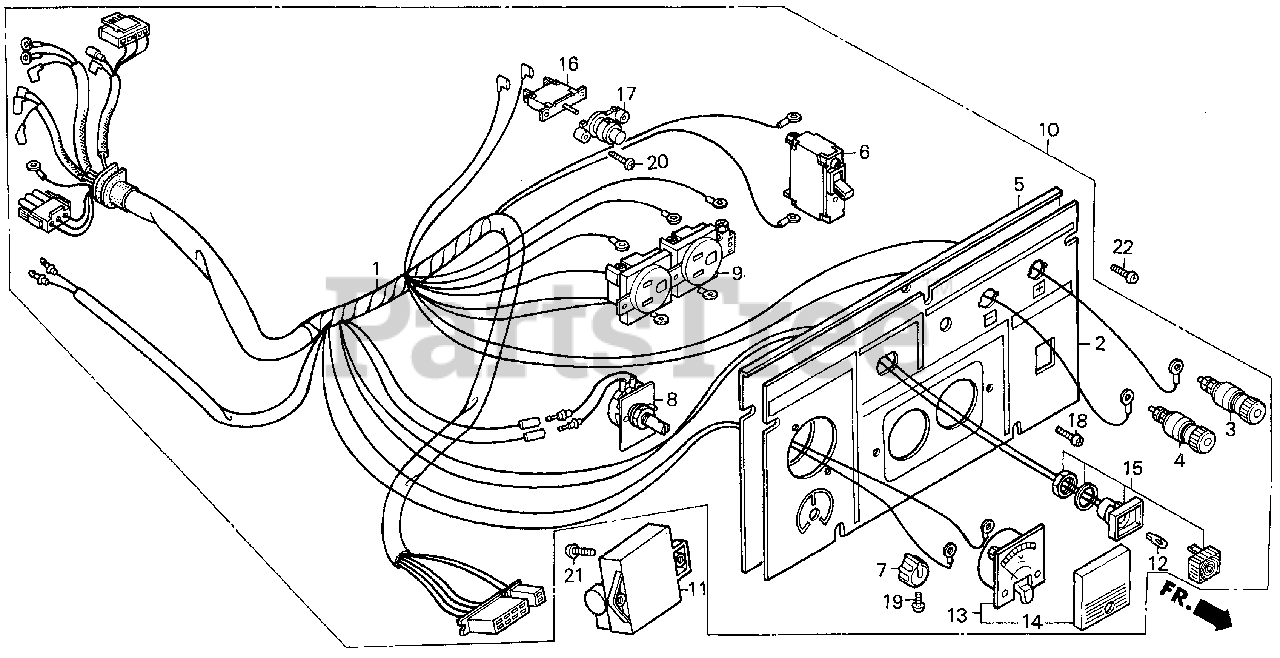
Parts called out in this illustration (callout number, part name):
1	WIRE HARNESS ASSY.
2	MARK, SWITCH PANEL
3	TERMINAL, D.C. OUT (+)
4	TERMINAL, D.C. OUT (-)
5	PANEL, CONTROL
6	BREAKER, CIRCUIT (17.5A)
7	KNOB, ADJUSTING
9	RECEPTACLE (15A/125V)
10	PANEL ASSY., CONTROL
10	PANEL ASSY., CONTROL (A)
11	REGULATOR UNIT, AUTOMATIC
12	BULB, WEDGE BASE (12V/2W) (TSD30) (STANLEY)
13	VOLTMETER ASSY.
14	LENS, METER
15	SOCKET ASSY., LAMP (GREEN)
16	PROTECTOR, CIRCUIT (DC)
17	LENS ASSY., PROTECTOR
18	SCREW-WASHER (4X10)
19	SCREW, PAN (3X8)
20	SCREW, PAN (3X12)
21	SCREW, PAN (5X8)
22	SCREW, PAN (5X12)
